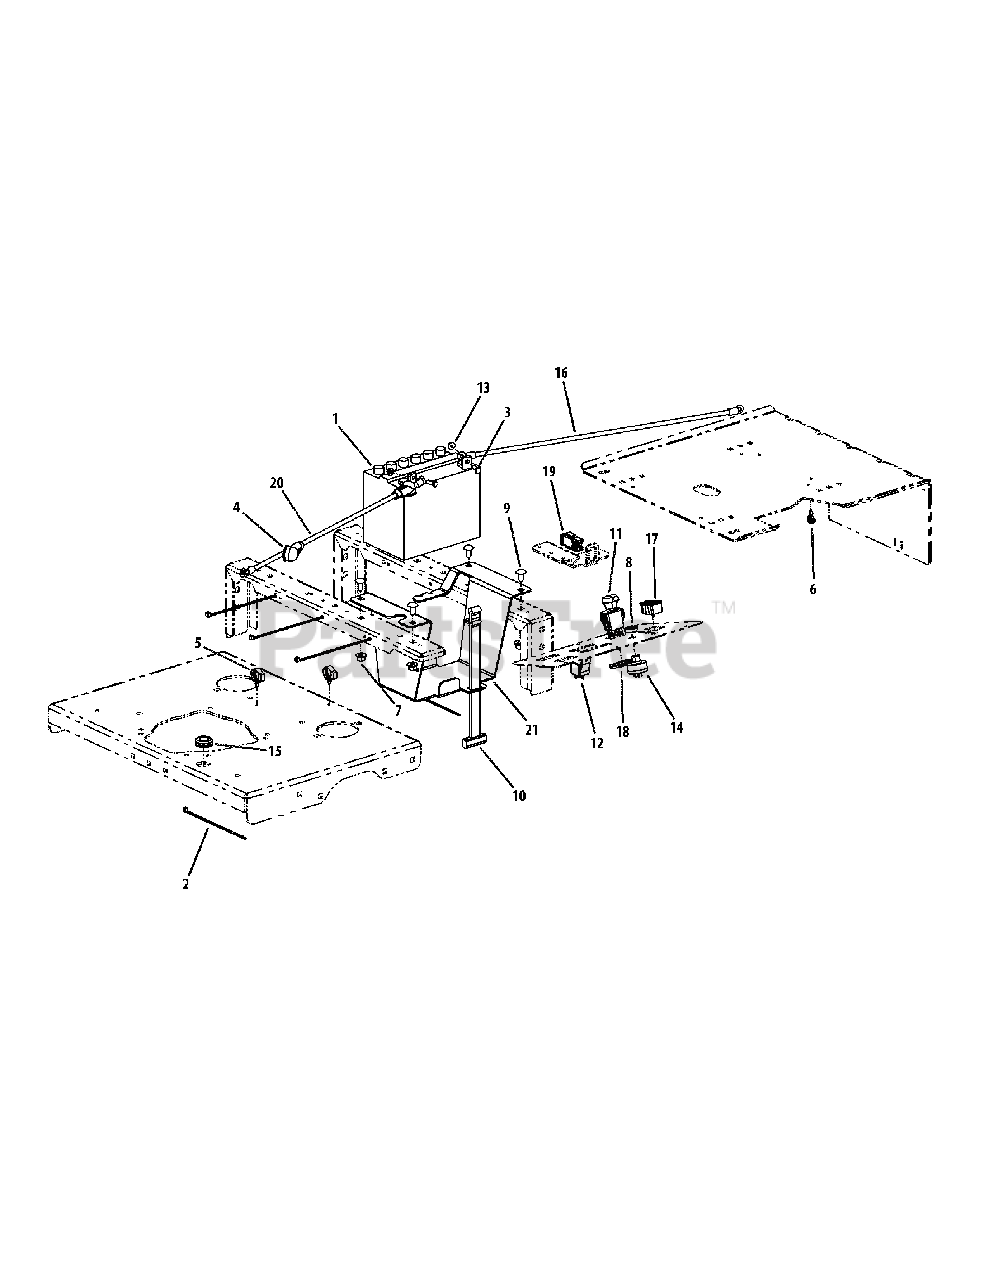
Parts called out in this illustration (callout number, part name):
1	Battery, 12V 225CCA 30 Min
2	Tie, Cable, 3/16 x .05 x 7.4"
3	Screw, Hex, Cap, 1/4-20 x .75
4	Boot, 1" OD Rubber Battery-PST, Red
5	Electrical Conduit Clip, 5/8
6	Electrical Conduit Clip, 3/8
7	Flange Lock, Hex Nut, 3/8-16
8	Nut, W/Cap, 5/8-32 Ignition
9	Carriage Bolt, 3/8-16 x .75 Long
10	Strap, Battery
11	Switch, Electric, PTO
12	Relay, 12V 40A
13	Lock Nut, 1/4-20
14	Switch, Ignition, 6 Pin
15	Grommet, .75 ID
16	Cable, Battery Red, 34"
17	Meter, Hour
18	Bracket, PTO Switch Retainer
19	Switch, Safety N.O./N.C.
20	Cable, Battery, Red, 42"
21	Battery Bracket
